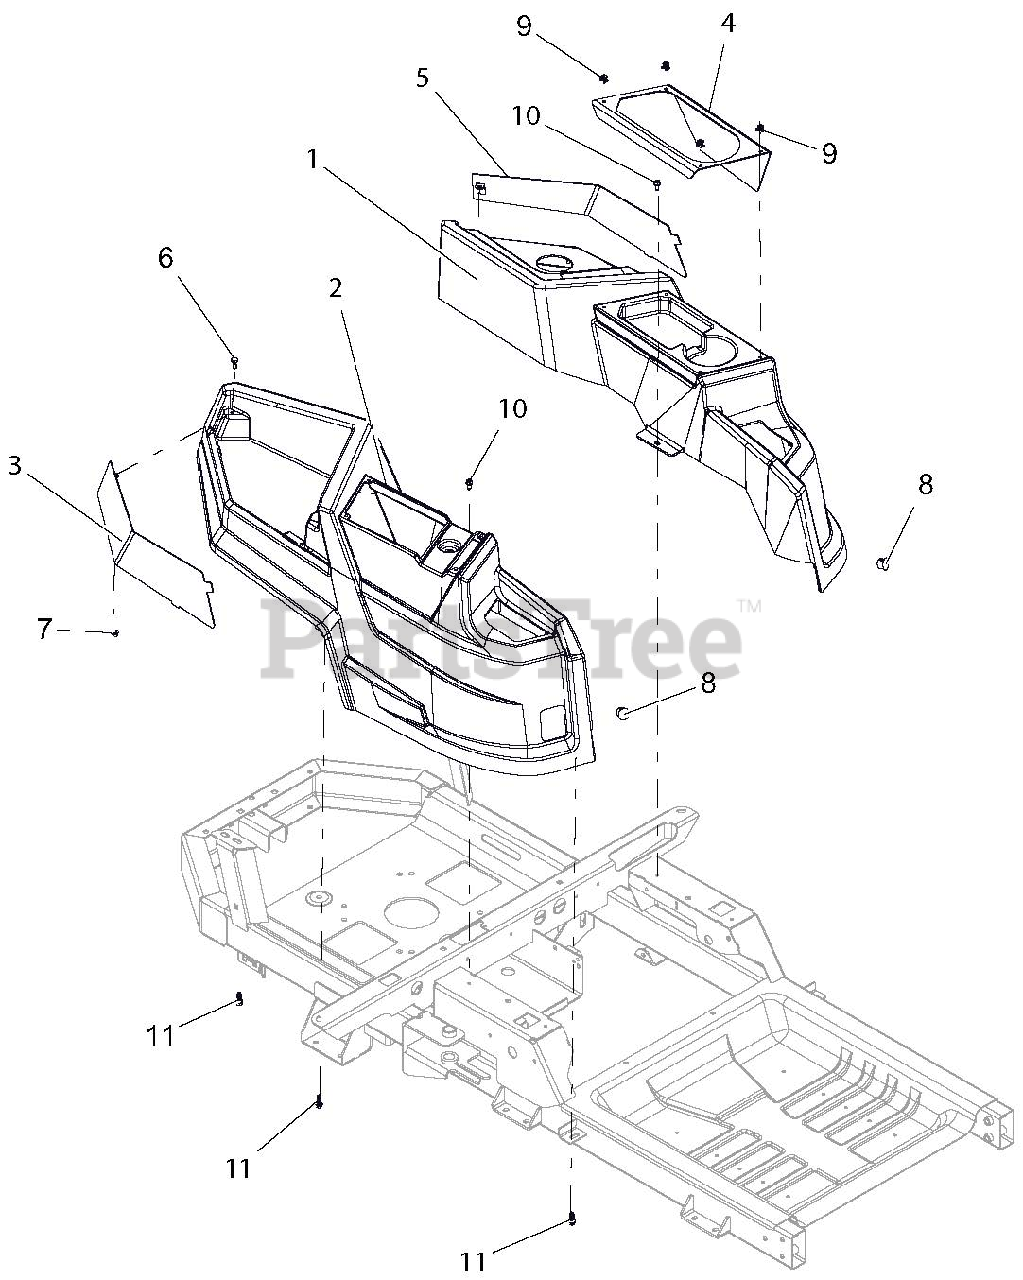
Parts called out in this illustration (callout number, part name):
1	FENDER, LH -ZOOM
2	FENDER, RH -ZOOM
3	WLMT, FENDER BLOCKOFF-RH
4	PANEL, CUPHOLDER/STORAGE (LH)
5	WLMT, FENDER BLOCKOFF-LH
6	BLT-HEX.25-20X.62 BLKZC ROHS
7	@NUT-LK-TOP-FLG .25-20 YWZC
8	PLUG, HOLE .75 (BLACK)
9	RIVET, PLASTIC .195 DIA.
10	SCR-TAP .25-20X.50 HWH TR YWZ
11	SCR-.312X.75 #14H H/W/H H/L CZ
